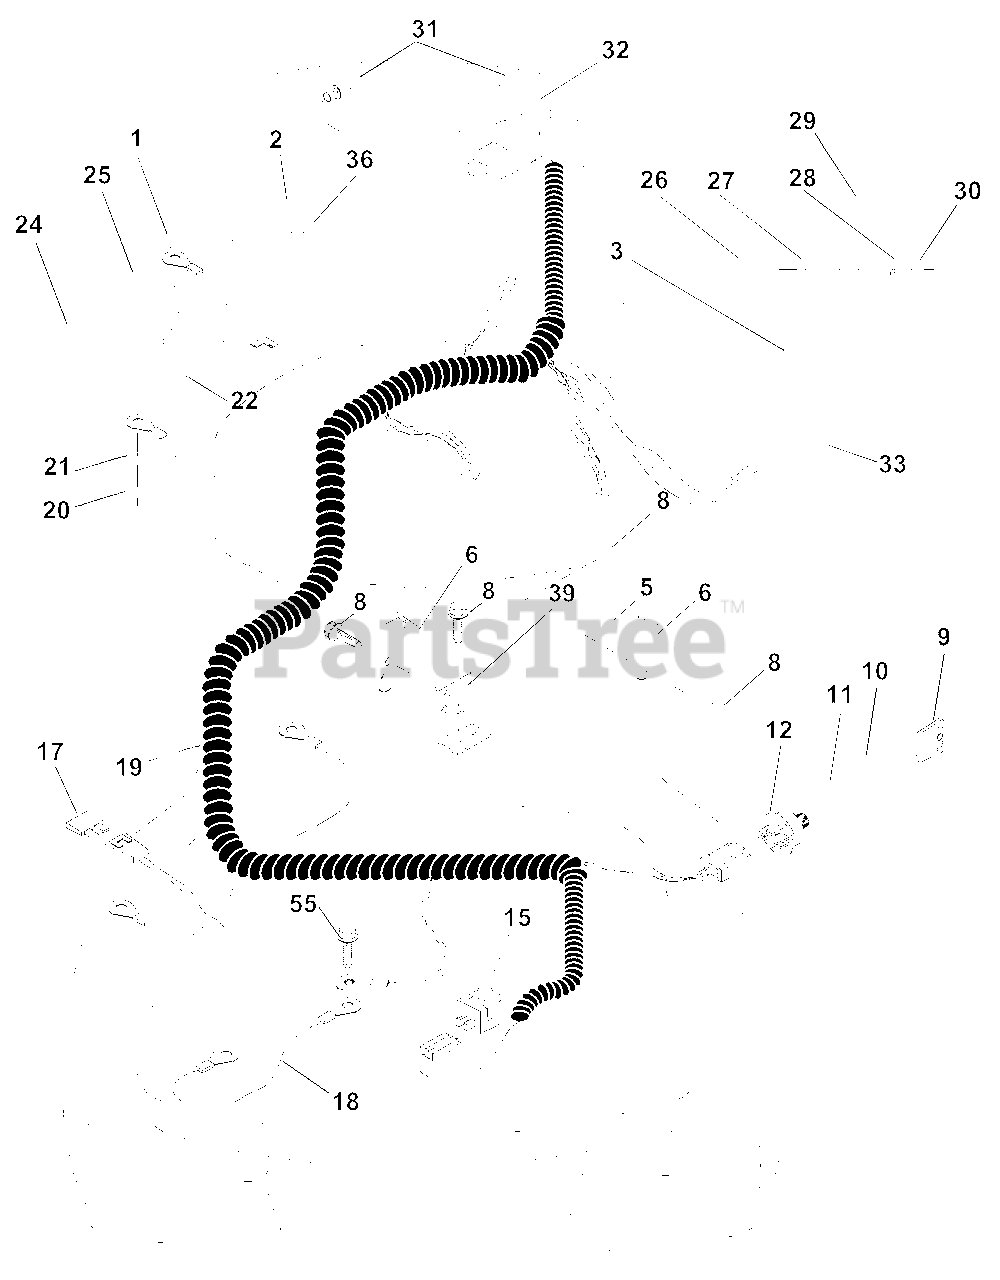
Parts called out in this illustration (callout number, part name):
1	Nut, Hex, Keps 1/4-20
2	Assembly, Cable
3	Battery
5	Bracket, Switch
6	Switch, Interlock, 4 Terminal
8	Screw, Hex Head, Self-Tapping #10-24 x 1/2
9	Key, Molded
10	Cover, Ignition Key
11	Nut, Ignition
12	Switch, Ignition
15	Switch, Plunger
18	Assembly, Cable
19	Harness, Ignition
20	Nut, Hex, Jam 1/4-20
21	Washer, Lock 1/4
22	Bolt, Hex, Fin. 1/4-20 UNC x 1/2 Grade 5
24	Cover, Terminal
25	Solenoid
26	Bolt, Hex Head 1/4-20 UNC x 3/4
27	Washer 9/32 x 5/8 x 16 Gauge
28	Washer, Lock 1/4
29	Cap, Battery
30	Nut, Hex, Fin. 1/4-20 UNC
31	Bulb, Light
32	Harness, Headlight
33	Switch, Light
36	Washer, Lock, Internal Tooth 1/4
39	Bracket Switch Clutch
55	Screw Thdrol 5/16 -18 x 1/2
